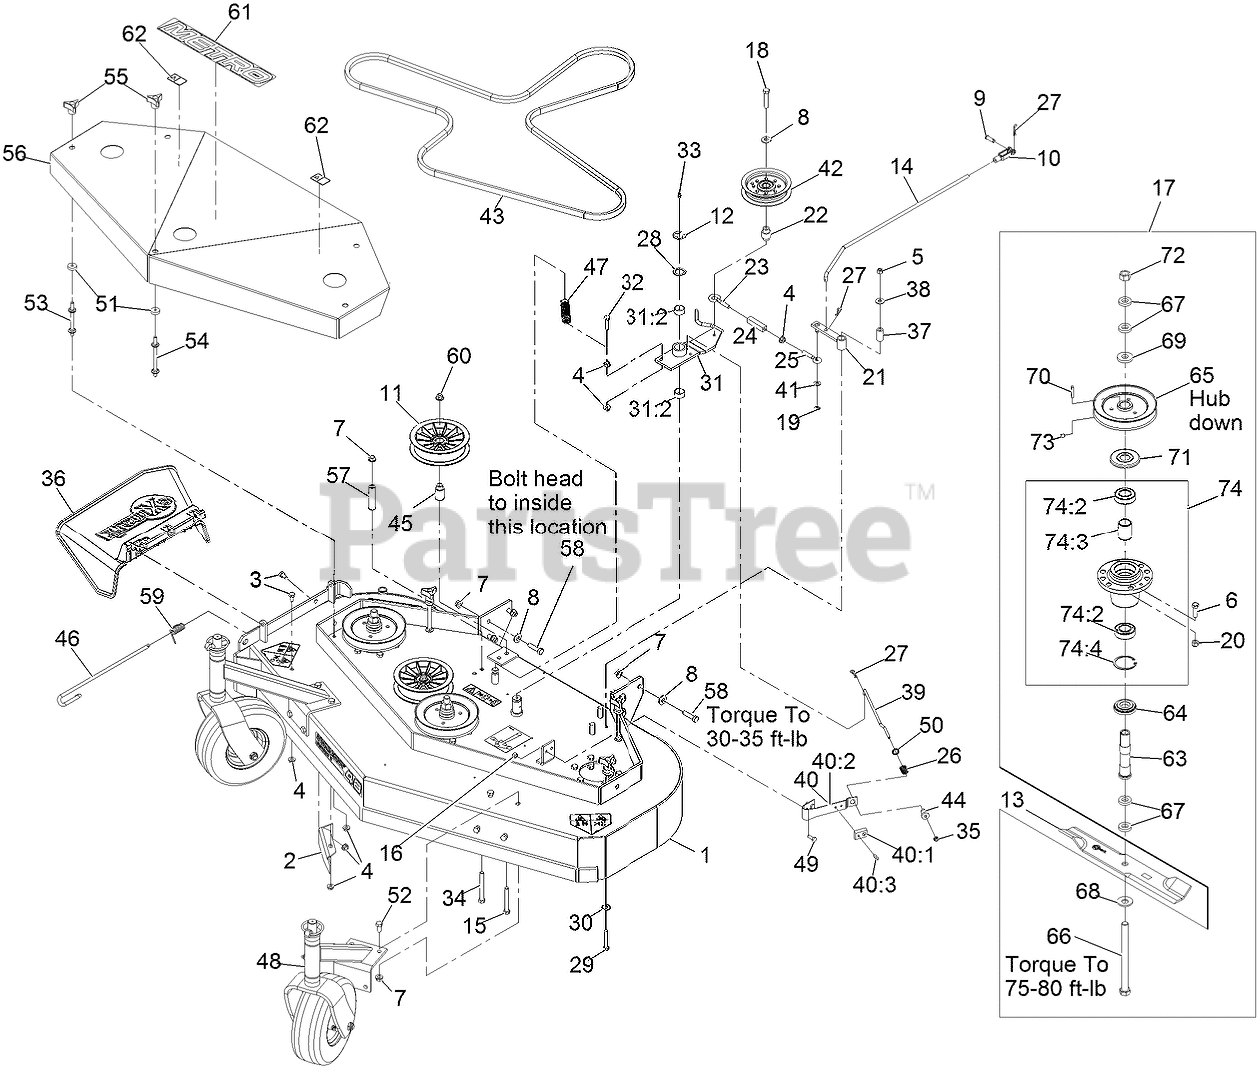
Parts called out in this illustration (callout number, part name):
1	DECK-SERVICE, 48
2	BAFFLE-DOGLEG
3	SCREW-HH
5	NUT-LOCK, NI
6	SCREW-HH
7	NUT-HHF, WHIZ
8	WASHER-BELLEVILLE
9	PIN-CLEVIS
10	YOKE-ADJUSTABLE
11	PULLEY,IDLER 5
12	RING-RETAINING, EXT
14	ARM-ASSIST, LINKAGE
15	SCREW-HH
16	NUT-LOCK, NI
17	ASM, CUTTER HOUSING OUTER
18	SCREW-HH
19	RING-RETAINING, EXT
20	NUT-LOCK, NI
21	ARM-ASSIST, 32/36
22	BUSHING-ENGAGEMENT
23	EYEBOLT-THREAD, LH
24	BODY-TURNBUCKLE
25	EYEBOLT-THREAD, RH
26	SPRING-COMPRESSION
27	PIN-COTTER
28	WASHER-SPINDLE
29	SCREW-HH
30	WASHER-SPRING
31	IDLER ARM ASM
31:2	SLEEVE-BEARING
32	SCREW-HH, SPECIAL
33	FITTING-GREASE
34	SCREW-HH
35	NUT-LOCK, NI
36	CHUTE DEFLECTOR XRK M056
37	TUBE-PIVOT
38	WASHER-FLAT
39	ROD-BRAKE
40	PAD AND SPRING ASM
41	WASHER-PLAIN
44	SPACER-FLANGED
45	BUSHING-IDLER
46	PIN-CHUTE
47	SPRING-EXTENSION
48	ASM-CASTER MNT W/WEIGHT
49	SCREW-HH
50	RING-PUSH ON
52	SCREW-HH
53	STUD-SHIELD, BELT (SHORT)
54	STUD-SHIELD, BELT (LONG)
55	KNOB-3 PRONG
56	ASM,SHIELD W/DECALS 48 METRO
58	SCREW-HH
59	SPRING, TORSION
60	NUT-HF, NI
61	DECAL-METRO
62	DECAL-WARNING
63	TUBE-SPINDLE, SHORT
64	SPACER-GUARD, BOTTOM
65	SHEAVE
66	SCREW-CAP, HH
68	WASHER-SPRING
69	WASHER-RETAINER, SHEAVE
71	GUARD-BEARING, TOP
72	NUT-HEX
73	SETSCREW
74	Cutter Housing ASM
74	KIT, CUTTER HOUSING
74:2	BEARING-JACKSHAFT
74:3	SPACER-BEARING
74:4	RING-SNAP
